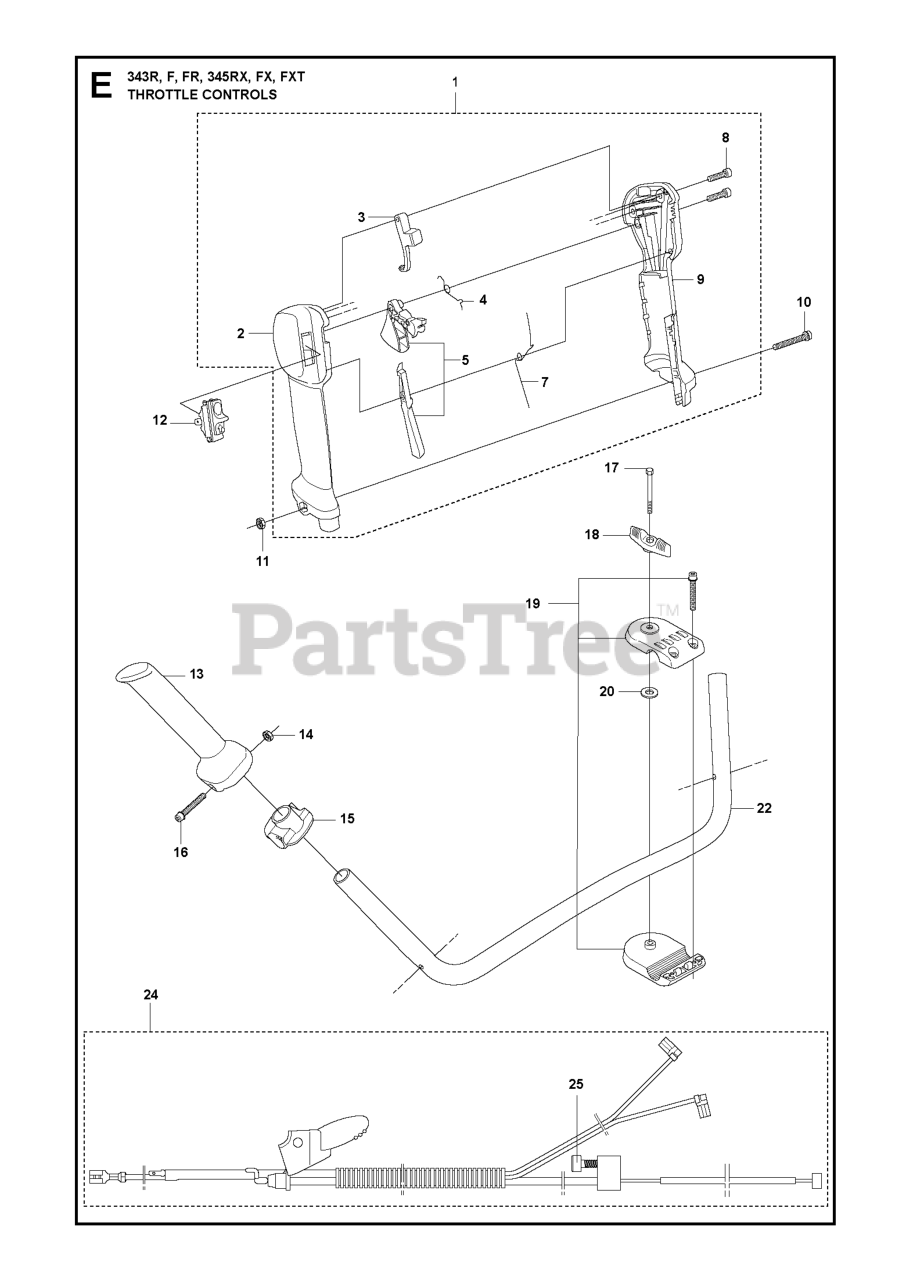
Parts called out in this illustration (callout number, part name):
1	THROTTLE HANDLE ASSY
2	HANDLE HALF LEFT
3	LOCKOUT STARTER THROTTLE
5	THROTTLE CONTROL
9	HANDLE HALF RIGHT
10	SCREW
12	STOP BUTTON
14	NUT M6M M5
17	%SCREW
19	HANDLEBAR BRACKET KIT
24	WIRING ASSY
25	SCREW
